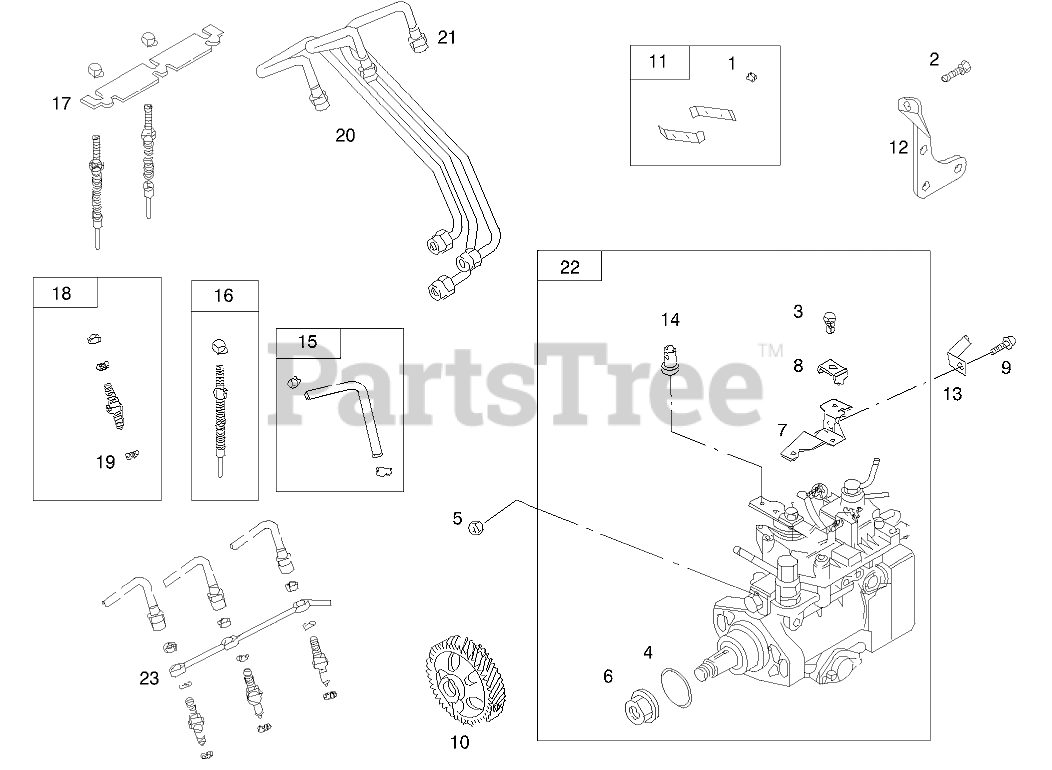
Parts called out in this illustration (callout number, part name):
1	SCREW-HEX
2	SCREW-HEX
3	SCREW-HEX
4	O-RING
4	NIPPLE ASM
5	NUT-HEX, METRIC
5	VALVE ASM
6	NUT-HEX, METRIC
7	BRACKET-CLAMP, CASING
8	CLAMP-CASING
9	SCREW-HEX
9	GASKET-SET
10	GEAR-DRIVE
11	CLAMP
12	BRACKET-SUPPORT
13	Bracket-Support
14	CLAMP-SWIVEL
14	VALVE OVERHAUL KIT
15	HOSE / CLAMP ASM
15	SHAFT-GEAR
16	PLUG-GLOW
17	STRAP-PLUG, GLOW
18	NOZZLE-INJECTOR
19	SEAT-INJECTOR
20	PIPE-INJECTOR, NO. 2
21	PIPE-INJECTOR, NO. 3
22	PUMP-INJECTION
23	PIPE-RETURN, FUEL
